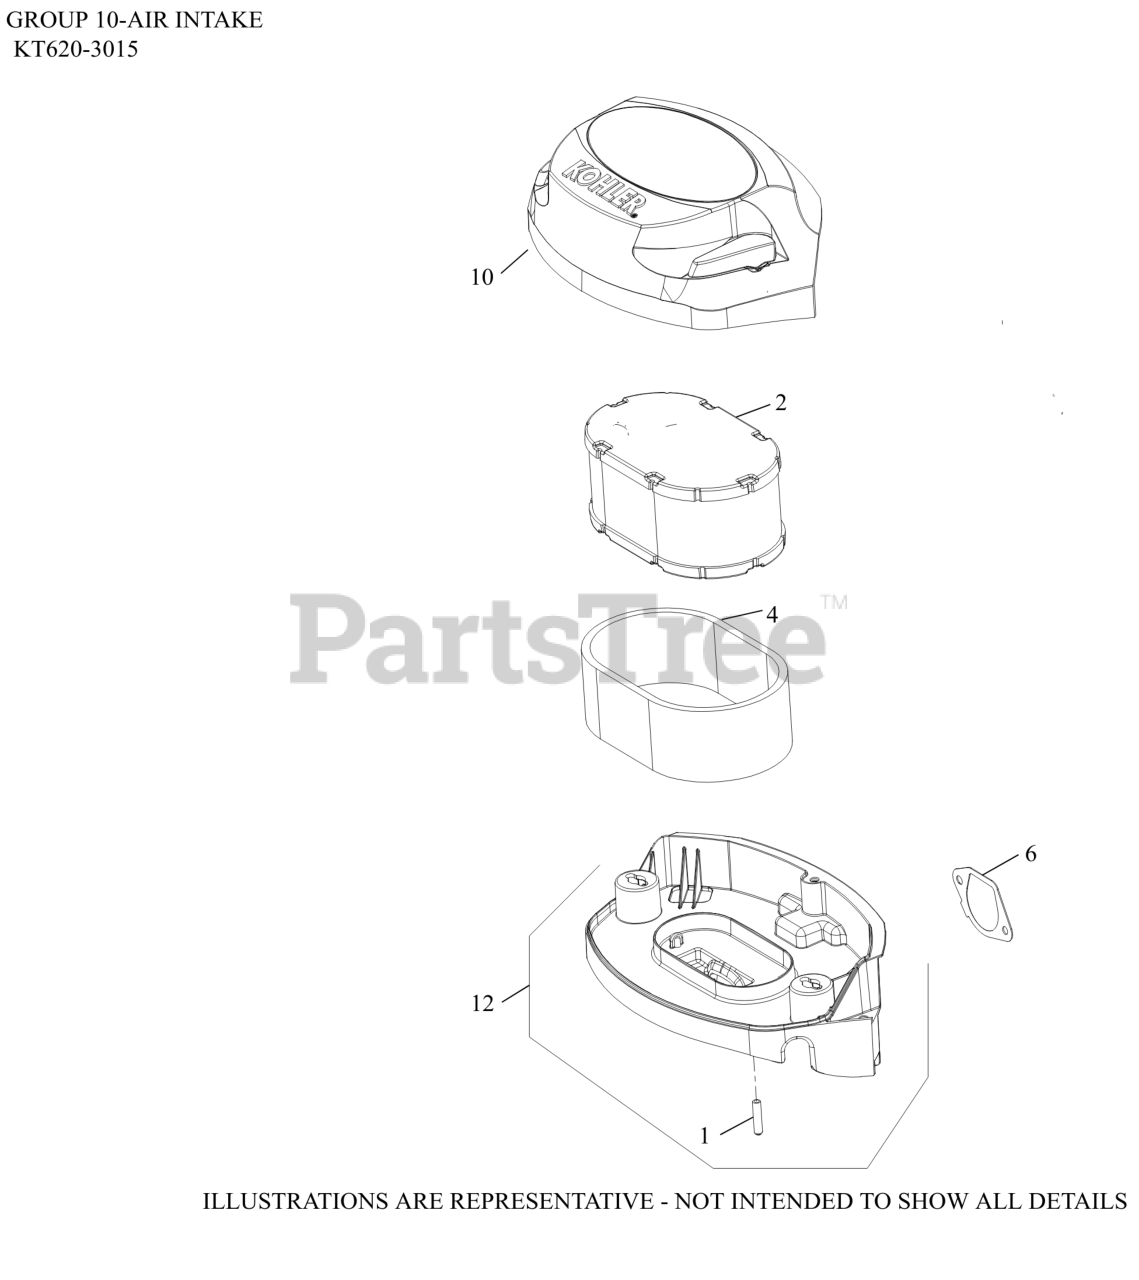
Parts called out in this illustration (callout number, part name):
1	CAP, MASKING
2	ELEMENT, AIR FILTER
4	ELEMENT, PRE-CLEANER
6	GASKET, AIR CLEANER BASE
10	COVER ASSY, AIR CLEANER
12	BASE ASSY, AIR CLEANER
